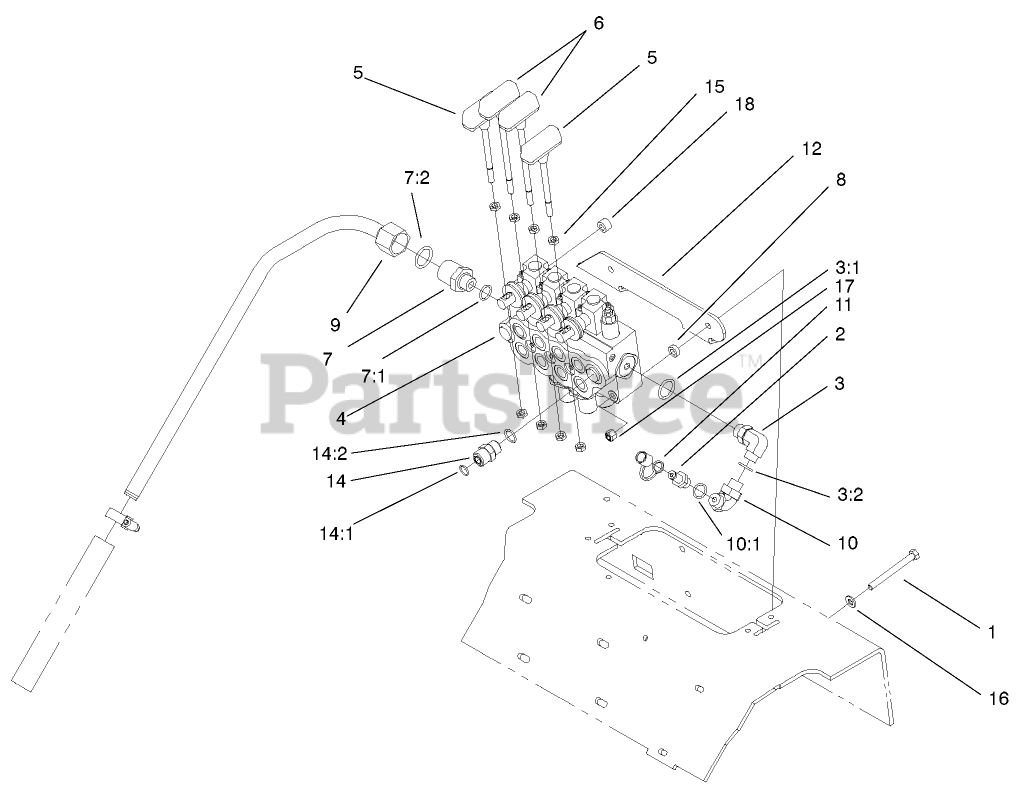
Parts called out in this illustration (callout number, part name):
1	SCREW-HH
2	NIPPLE-TEST
3	FITTING-HYD, 90 DEG
3:1	O-RING
3:2	O-RING
4	VALVE-HYD, 4-SPOOL
5	CYLINDER HANDLE ASM
6	DRIVE HANDLE ASM
7	FITTING-STR
7:1	O-RING
7:2	O-RING
8	SPACER
9	HYD TUBE ASM
10	FITTING-HYD, 90 DEG
10:1	O-RING
11	CAP-DUST
12	BRACKET-COVER, MOUNT
14	FITTING-STRAIGHT
14:1	O-RING
14:2	O-RING
15	NUT-HEX
16	WASHER-PLAIN
17	NUT-LOCK, NI
18	SPACER
